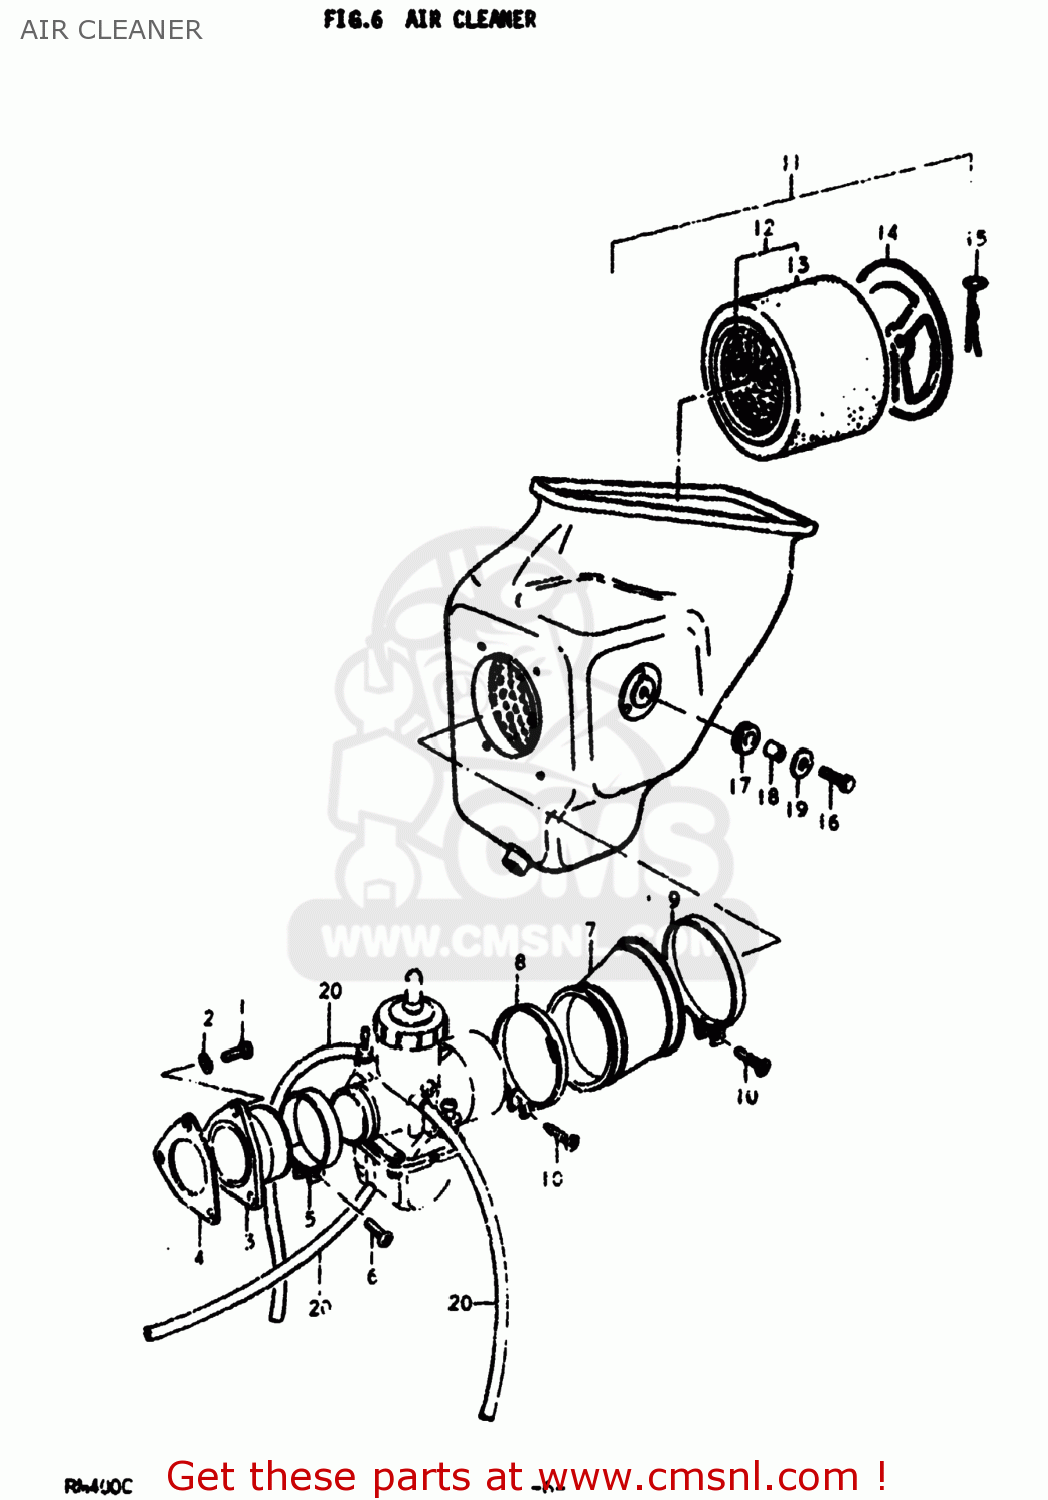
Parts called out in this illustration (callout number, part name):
1	BOLT, UPPER
2	WASHER,LOCK
3	PIPE,INTAKE
4	GASKET,INTAKE PIPE (NAS)
5	CLAMP
6	SCREW 5X20
7	HOSE,CARBURETOR AIR INLET
8	CLAMP
9	CLAMP
10	SCREW
11	CLEANER ASSEMBLY,AIR
12	FILTER ASSY
13	FILTER
14	CAP
15	SPRING,AIR CLEANER
16	BOLT, UPPER
17	CUSHION
18	SPACER (7X9X7)
19	WASHER (6.5X20X1.2)
20	HOSE
